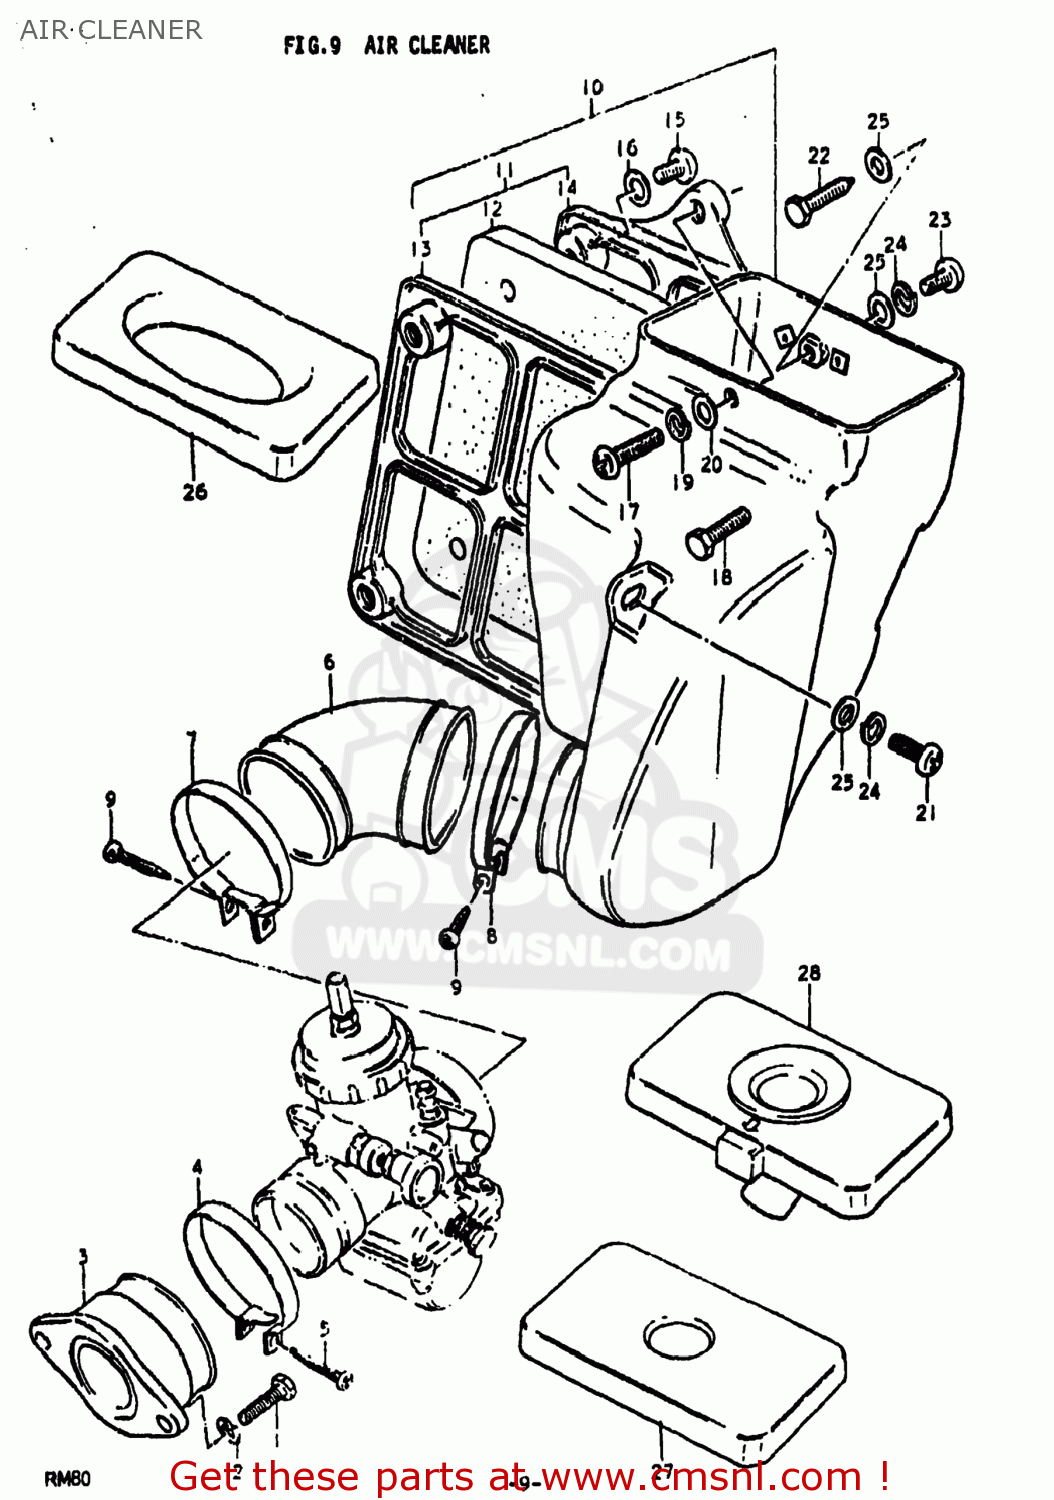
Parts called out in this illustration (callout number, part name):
1	BOLT
2	LOCK WASHER
3	PIPE,INTAKE
4	CLAMP
5	SCREW
6	TUBE,AIR CLEANER OUTLET
7	CLAMP
8	CLAMP
9	SCREW
10	CLEANER ASSEMBLY,AIR
11	FILTER,AIR CLEANER
12	FILTER
13	ELEMENT,AIR CLEANER
14	ELEMENT,AIR CLEANER
15	SCREW 6X12
16	WASHER 6MM
17	SCREW
18	BOLT, UPPER
19	LOCK WASHER
20	WASHER
21	SCREW
22	BOLT,UPPER
23	SCREW 6X12
24	LOCK WASHER
25	WASHER
26	CAP,AIR CLEANER
27	CAP,AIR CLEANER
28	CAP,AIR CLEANER
